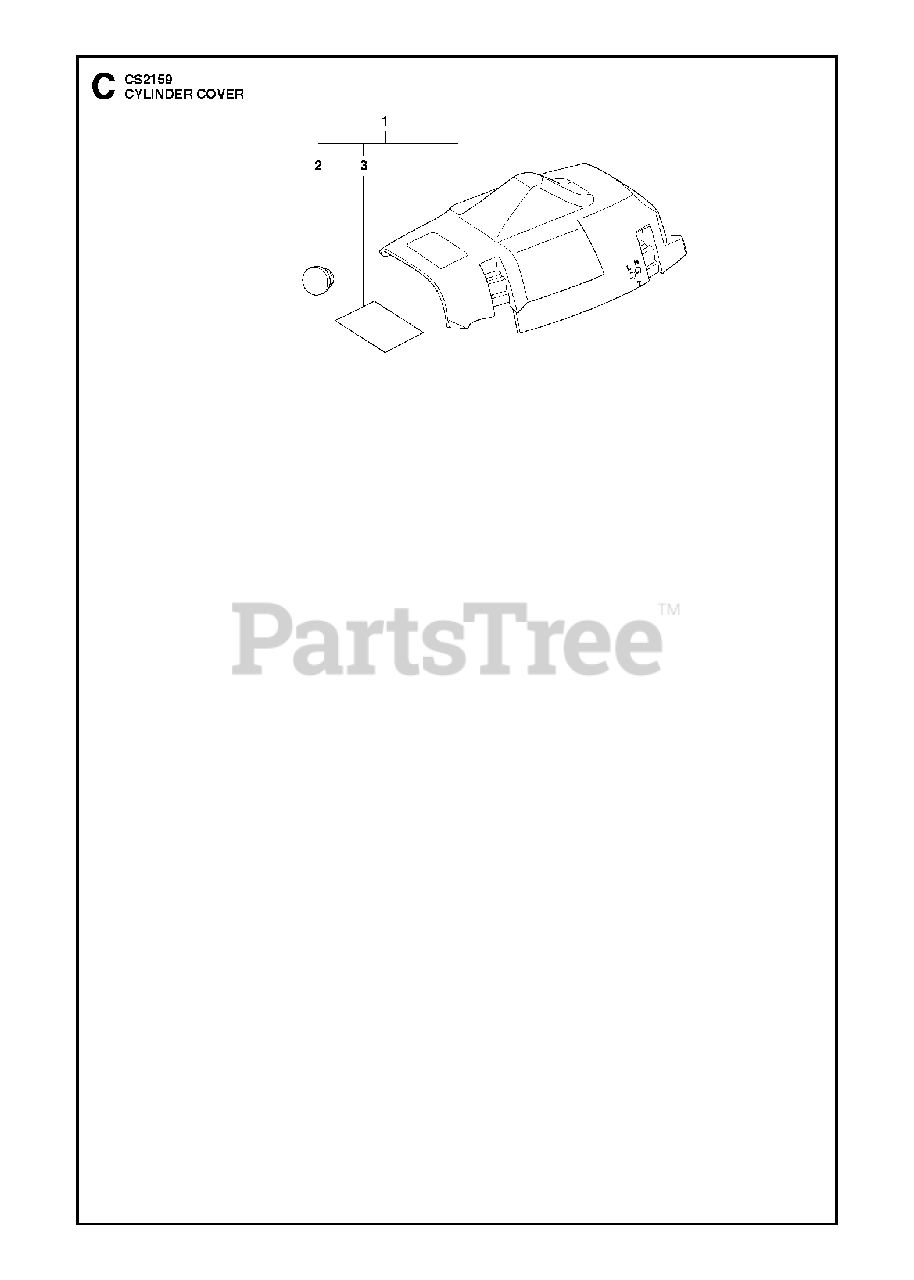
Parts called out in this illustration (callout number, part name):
1	CYLINDER COVER
2	PLUG
3	PROTECTOR
